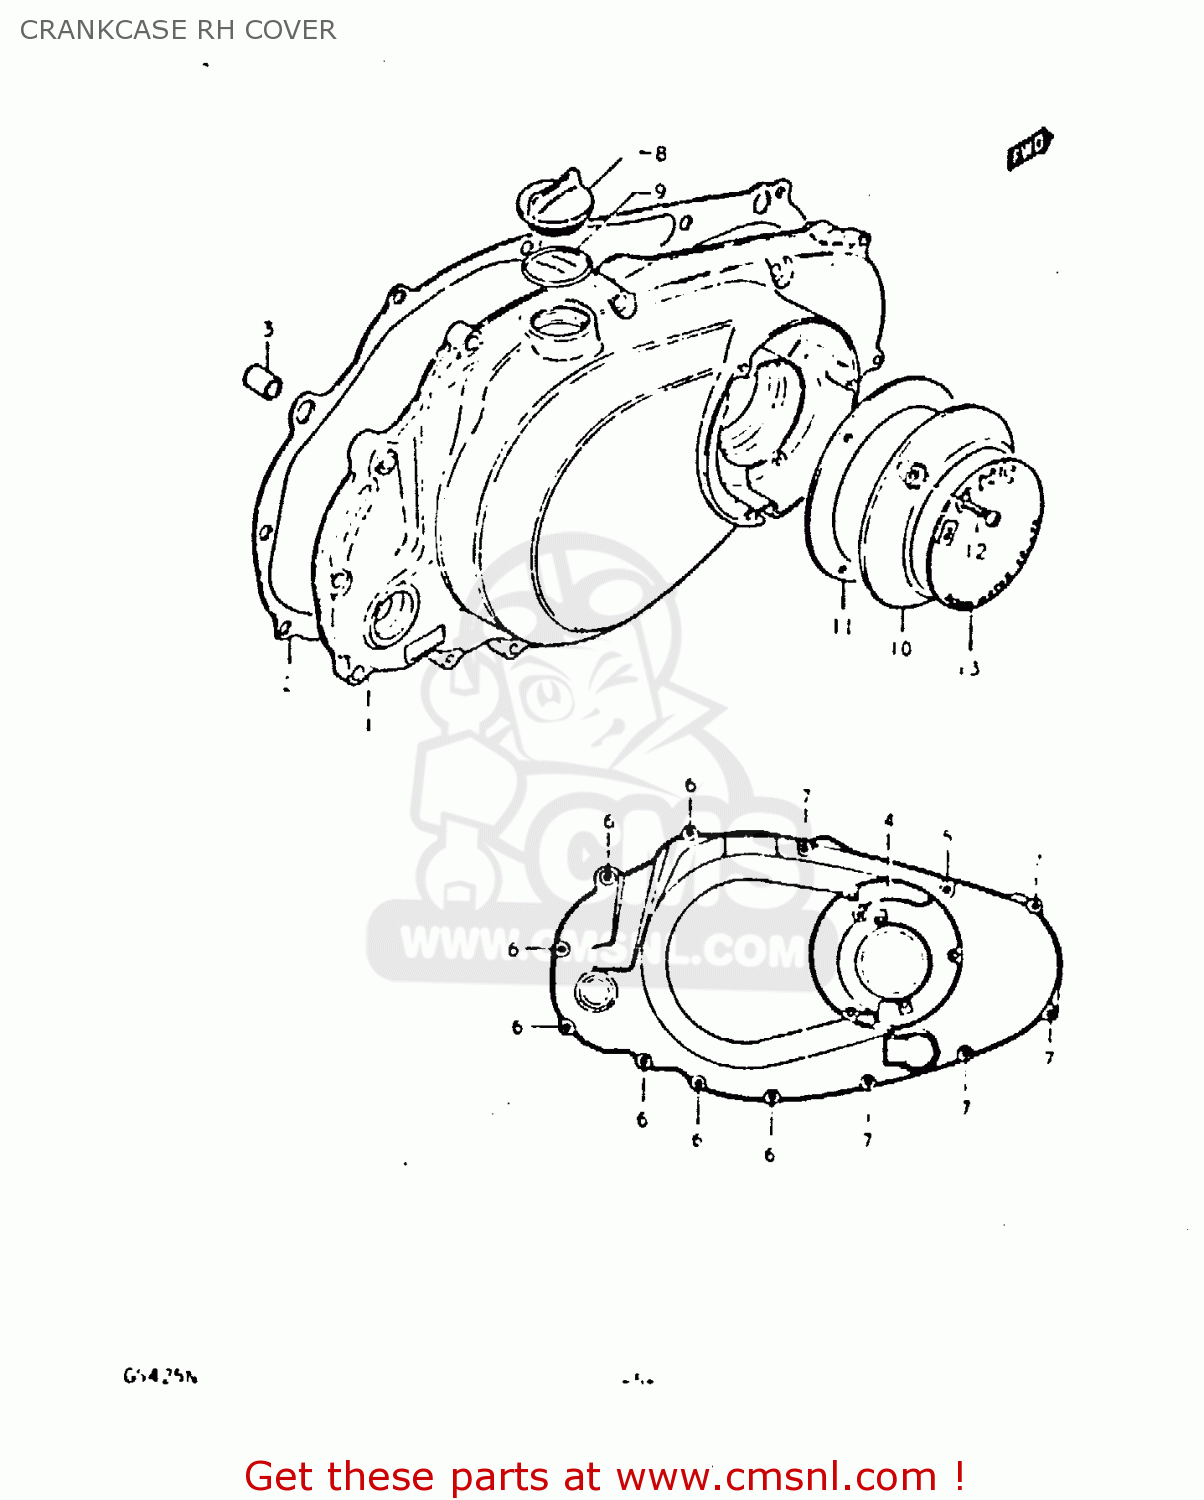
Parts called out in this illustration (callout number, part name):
1	COVER,CLUTCH
2	GASKET,CLUTCH COVER (MCA)
3	PIN
4	SCREW 6X60
5	SCREW (6X45)
6	SCREW (6X35)
7	SCREW
8	CAP
9	O RING(D:2.2,ID:32)
10	COVER,CONTACT BREAKER
11	GASKET,CONTACT BREAKER (MCA)
12	SCREW 5X20
13	EMBLEM
